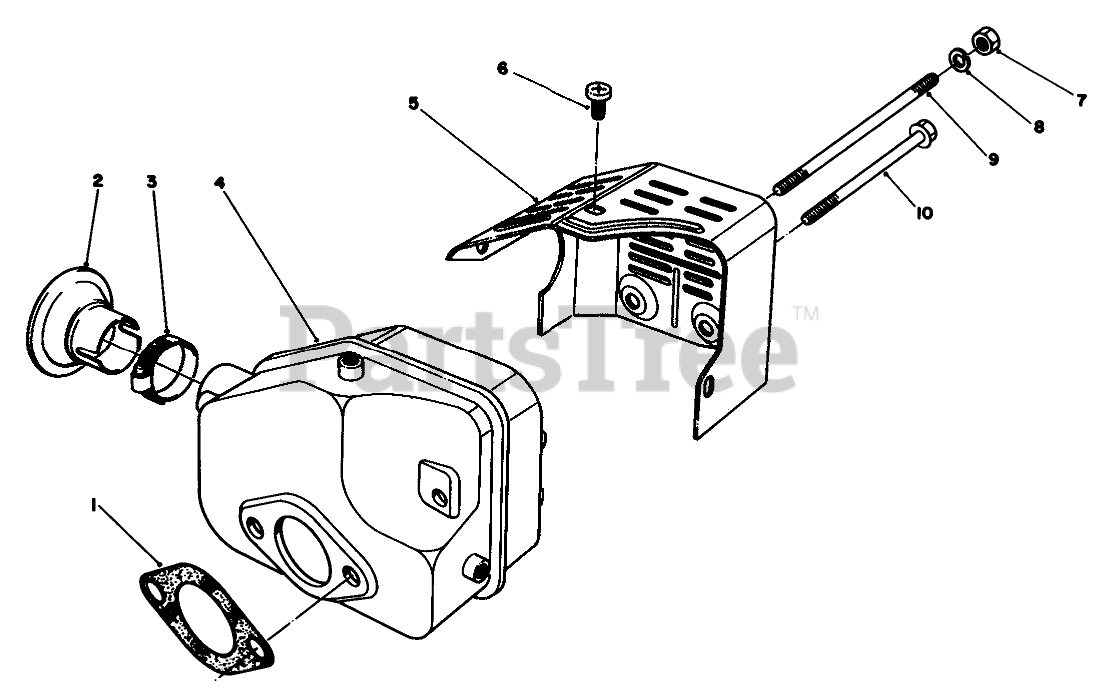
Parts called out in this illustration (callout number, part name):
1	GASKET
2	Arrestor-Spark
3	Clamp-Hose
4	Muffler
5	COVER
6	SCREW
8	WASHER-LOCK
